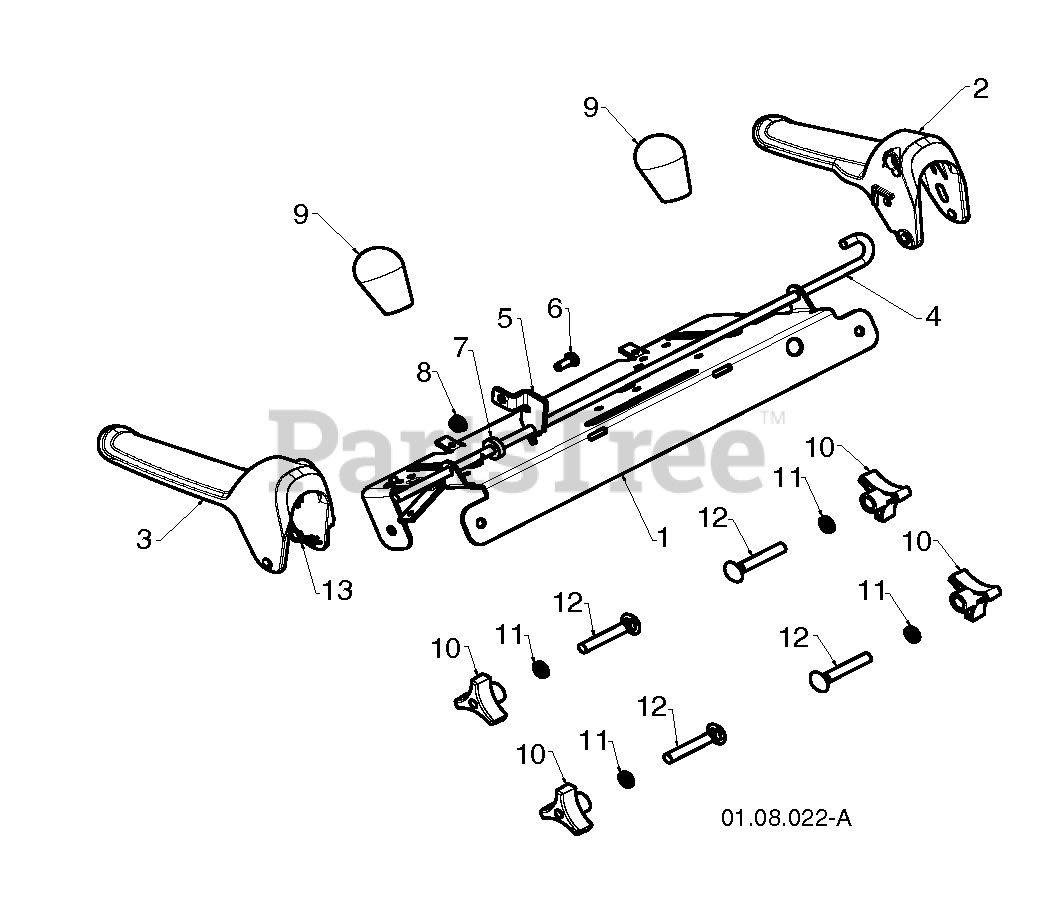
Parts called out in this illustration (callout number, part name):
1	PANEL.CONTROL.SNOW.BLACK
2	LEVER.CONTROL.LH.PL.BLACK
3	LEVER.CONTROL.RH.PL.BLACK
4	BAIL.CONTROL.INTERLOCK.SNOW
5	BRACKET.ARM.IMPELLER.ROD.YZ
6	BOLT
7	SPACER.CONTROL.LEVER
9	KNOB.OVERMOLD.DS.HUSQVARNA/BLK
10	KNOB.HANDLE.3/8.TRI-POINT.BLAC
11	WASHER
12	BOLT 3/8-16 X 2-1/4
13	SPRING RETAINER
